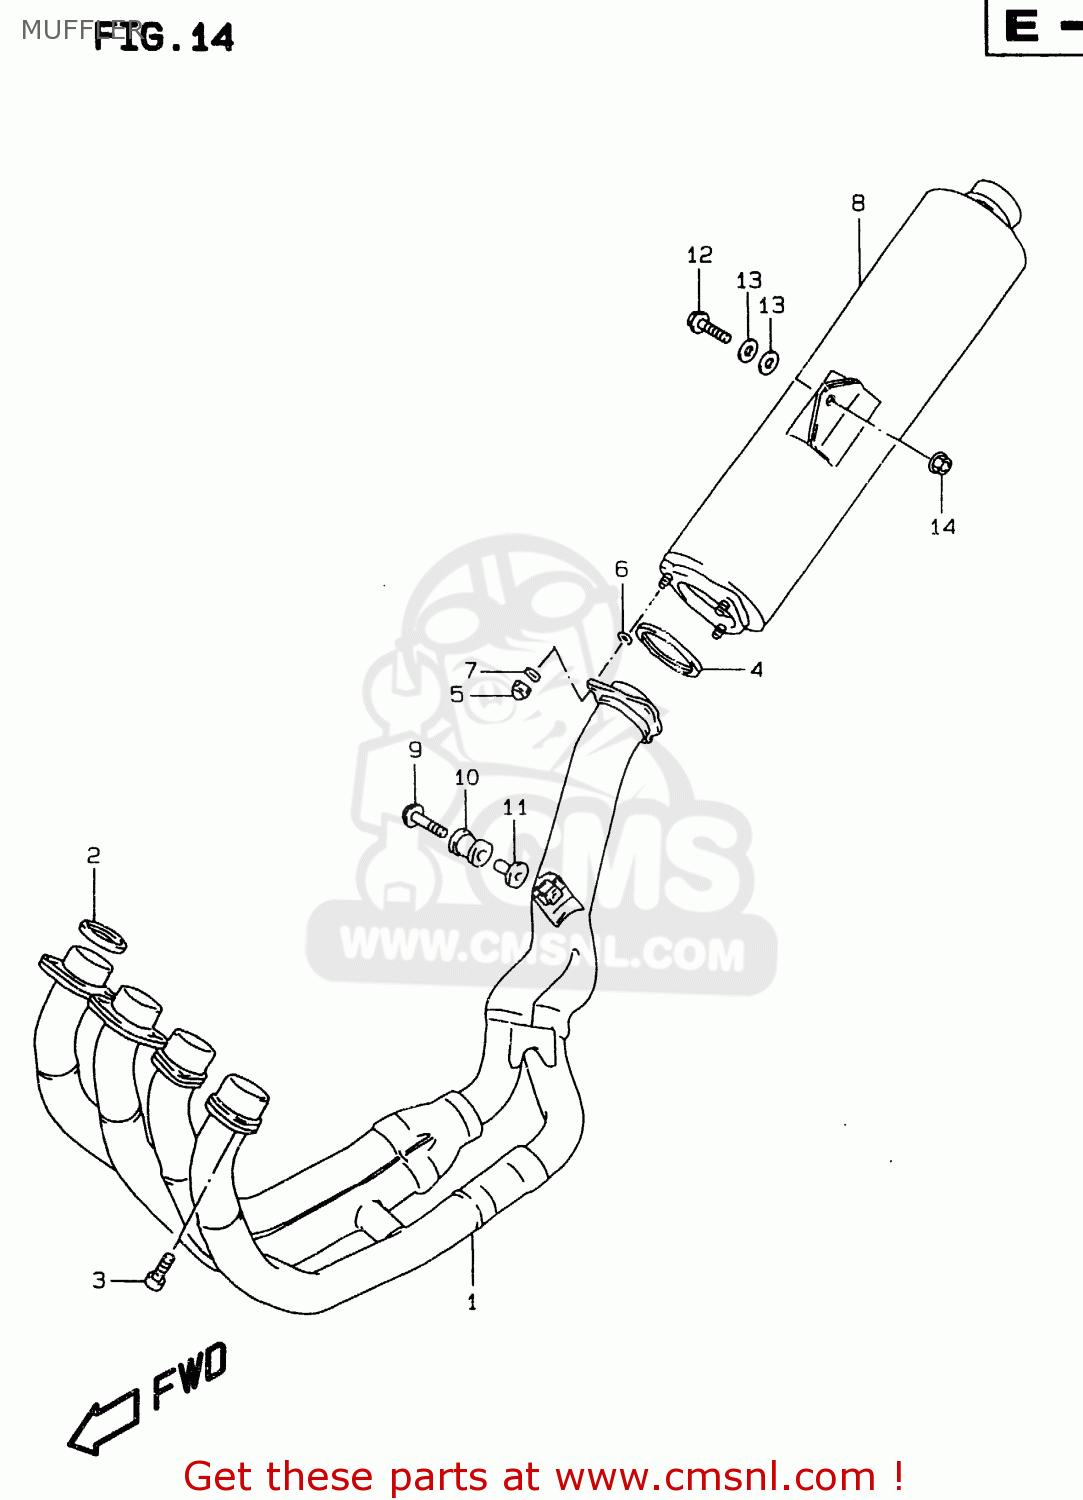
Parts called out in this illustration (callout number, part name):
1	EXHAUST COMP
2	GASKET,EXHAUST PIPE
3	BOLT
4	GASKET,MUFFLER JOINT
5	NUT
6	WASHER(8.5X18X1.6)
7	O RING(D:1.9,ID:7.8)
8	BODY,MUFFLER
9	BOLT 8X45
10	CUSHION
11	SPACER(8.6X12X24.2)
12	BOLT
13	WASHER (8.2X24X1.6)
14	NUT
